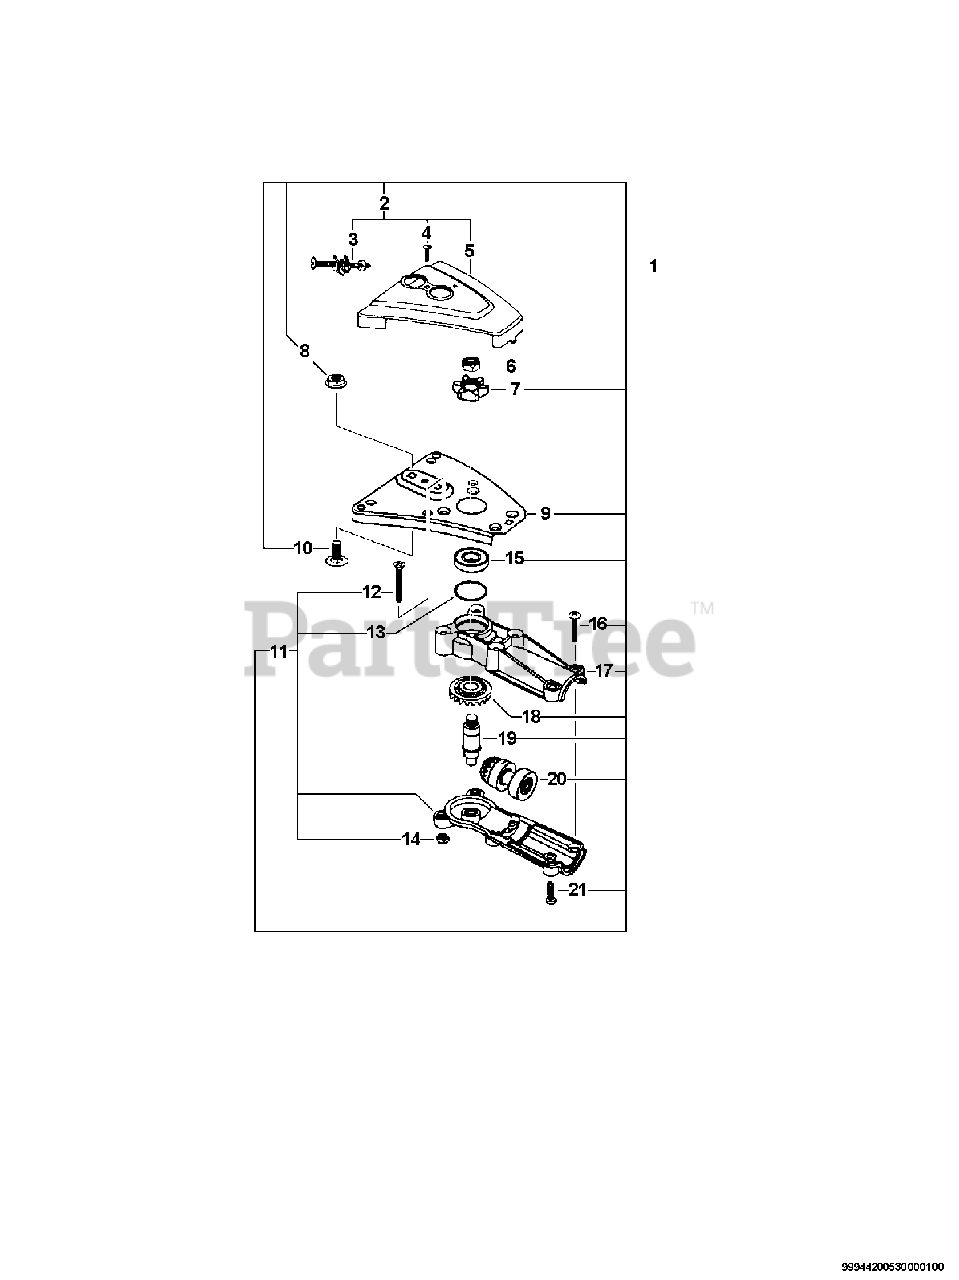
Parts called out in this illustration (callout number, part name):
1	CUTTING HEAD ASSY
2	SPROCKET COVER ASSY
3	ADJUSTER, CHAIN
4	SCREW - 8-32×1" - TORX PAN HEAD
5	GUARD, SPROCKET
6	NUT, HEX
7	SPROCKET
8	NUT - FLANGE
9	SAW BAR CARRIER
10	BOLT, CARRIAGE
11	CASE, GEAR - RIGHT
12	SCREW - TORX FLAT HEAD
13	SHIM 0.004"
14	NUT, LOCK 10-24 UNC
15	BEARING, BALL 6001 DDU
16	SCREW, TORX 10-24 UNC 1-1/4
17	CASE, GEAR - RIGHT
18	GEAR, BEVEL
19	SHAFT, GEAR
20	SHAFT, GEAR
21	SCREW - TORX PAN HEAD
